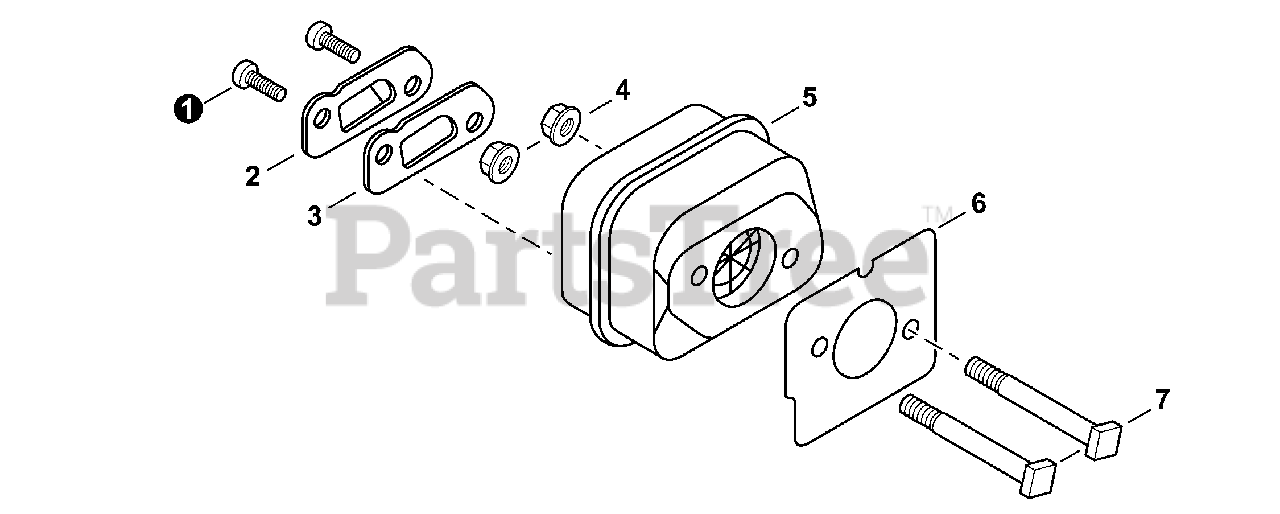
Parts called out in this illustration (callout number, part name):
1	SCREW 4×8
2	GUIDE, EXHAUST
3	SCREEN, SPARK ARRESTER
4	NUT, FLANGE M5
5	MUFFLER
6	GASKET, EXHAUST
7	BOLT 5×60
